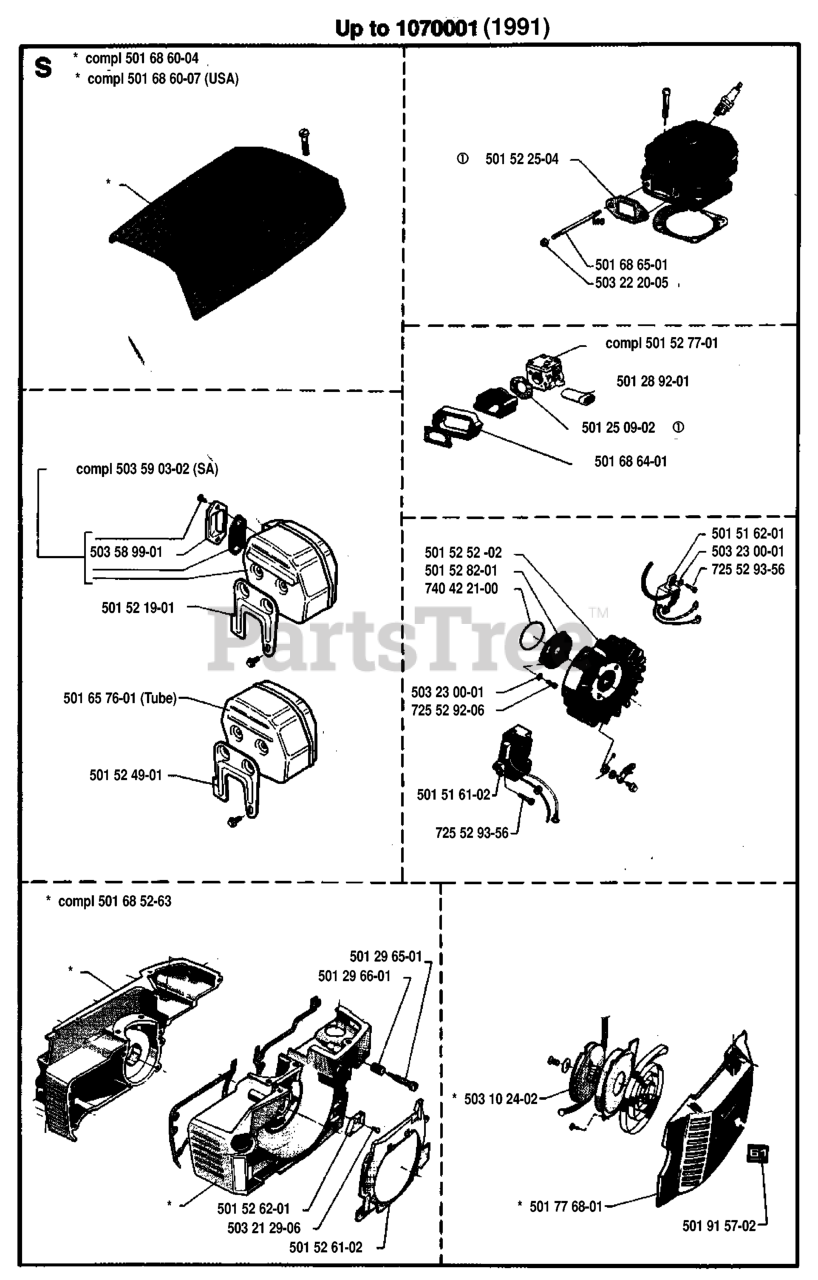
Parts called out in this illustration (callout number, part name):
1	BATTERY 12 VOLT 30 AMP WET
2	BOLT.HEX.1/4.X.3/4.DICHROMATE
4	LOCKWASHER
6	NUT
7	PLASTIC TUBE
8	BATTERY TRAY T
9	HOSE CLAMP T
10	BOLT 1/4-20 X 7.5
11	BATTERY HOLDDOWN FRONT MOUNT
12	NUT, PUSH NYLON 1/4" BATTERY
16	SWITCH INTERLOCK
19	LOCKWASHER
20	NUT
21	HARNESS LIGHT SOCKET
24	BATTERY CABLE GT
25	CABLE BATTERY 6 GA 22" W/16W
28	CABLE GROUND 6 GA 21" 90T BLK
29	RP.SWITCH.PLUNGER.NC.GRAY
30	SWITCH.IGNITION.4.POSITION
31	NUT IGNITION
32	COVER SWITCH KEY
33	KEY.MOLDED.GENERIC
40	IGN HARNESS
41	BOLT
42	TERMINAL COVER
43	SOLINOID
44	Nut, Keps Blk Hex 1/4-20 UNC
45	AMMETER
46	HOUR METER T
47	Screw 10-24 x 1/2 Black
50	SWITCH PTO 3 PDT
55	Screw 5/16-18 x 1/2 Hex, Self Tapping 5/16-18 x 1/2
70	HARNESS ENGINE
80	HARNESS, CLUTCH
